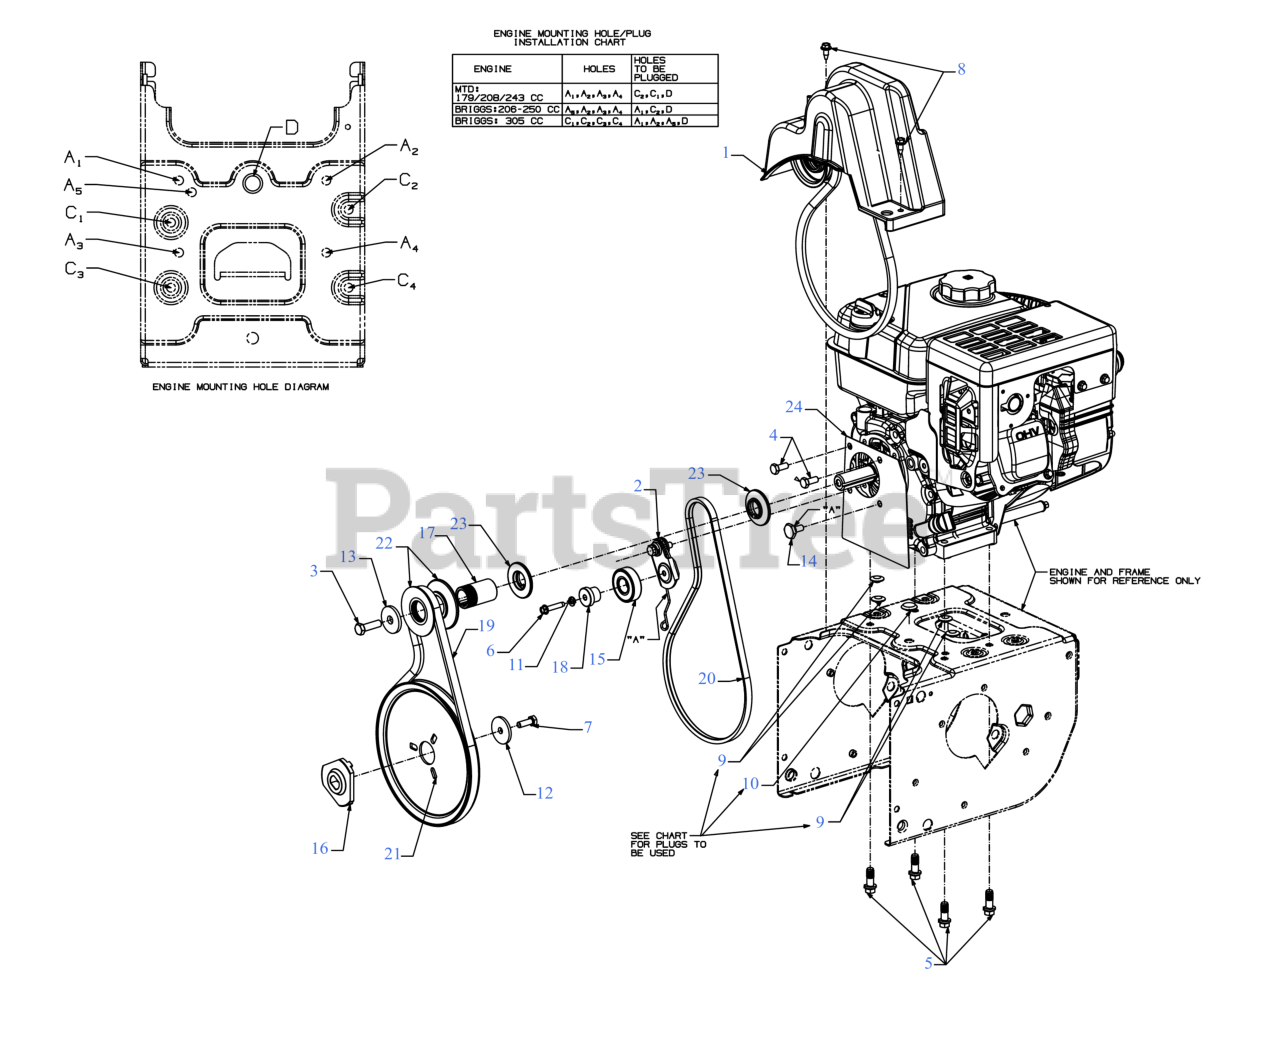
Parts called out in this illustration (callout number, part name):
1	BELT COVER (SMALL BLOCK)
3	SCREW 3/8-24X1.25
4	SCREW 5/16-24 x .750 GR5
5	SCREW 3/8-16 x 1
6	SCREW 1/4-20 x 1.25
7	SCREW 5/16-24 x .875 GR5
8	SCREW 1/4-20X.625
9	PLUG-3/8 DIA ID x 3/32
10	PLUG-1/2 ID x 3/32
11	LOCK WASHER
12	FLAT WASHER
13	FLAT WASHER .45 x 1.5 x .172 HT
14	SHOULDER SCREW
15	BALL BEARING
16	ADAPTER PULLEY .75 DIA W/DD
17	PULLEY SPACER
18	SHOULDER SPACER
19	V-BELT .500 x 35.00LG
19	Cub Cadet AUGER BELT
19	Genuine Factory Parts AUGER BELT
20	V-BELT 3L 34.18
20	Cub Cadet TRANSMISSION BELT
20	Genuine Factory Parts TRANSMISSION BELT
21	AUGER PULLEY
22	HALF PULLEY 4L V x 2.6 OD
23	HALF PULLEY-3/8 V x 1.7160
24	COVER PLATE (POWDER BLACK)
